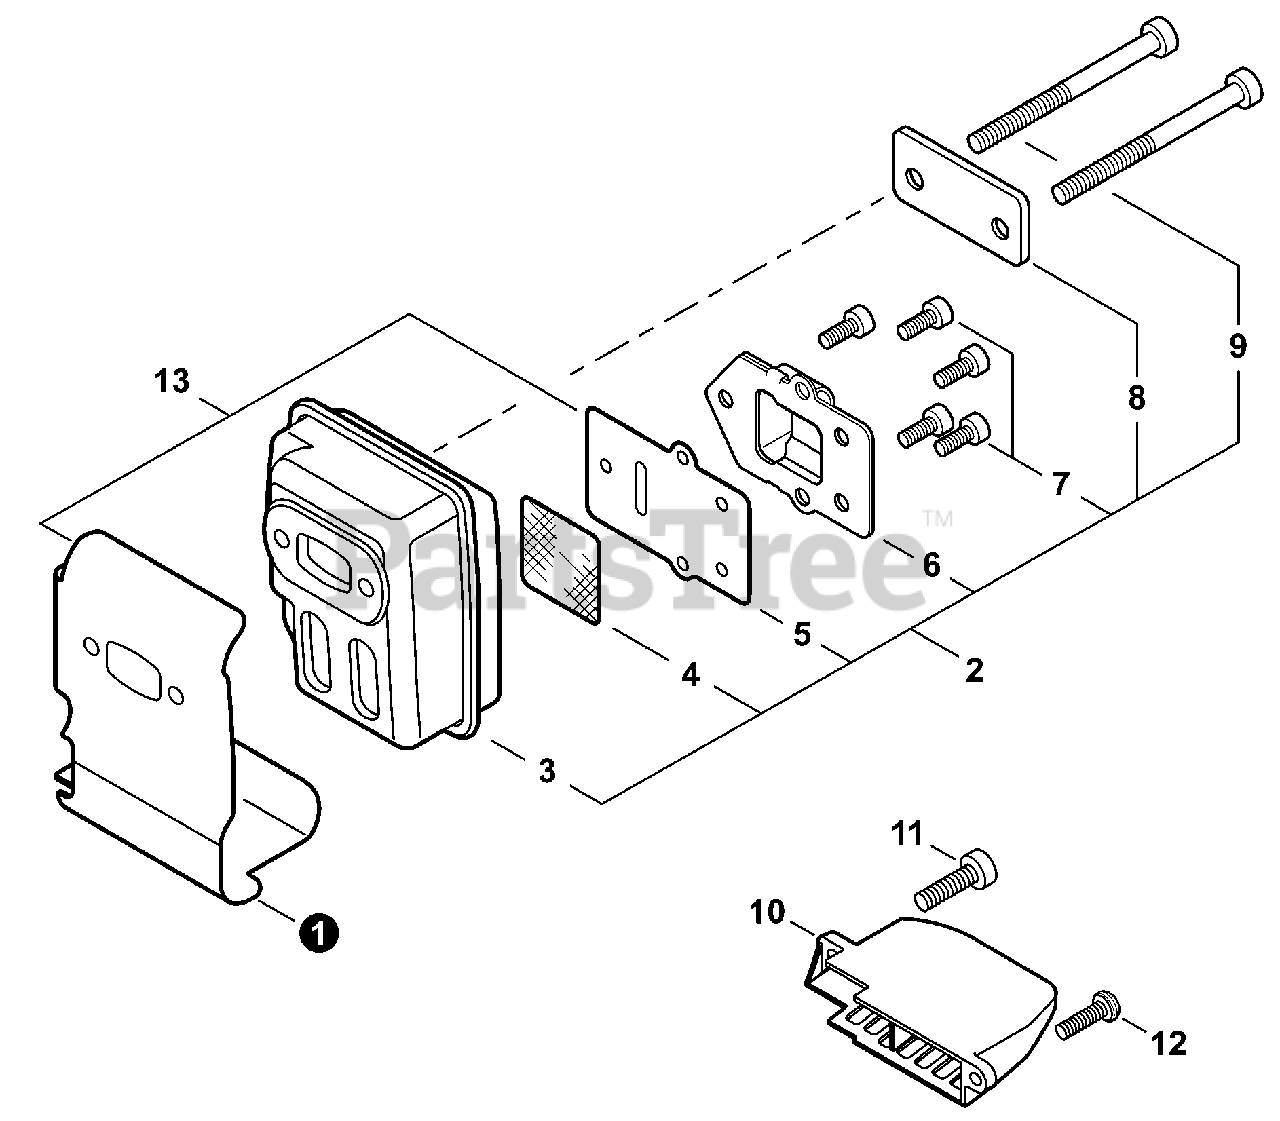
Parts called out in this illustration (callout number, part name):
1	HEAT SHIELD, EXHAUST
2	MUFFLER ASSY
3	MUFFLER
4	SCREEN, SPARK ARRESTER
5	GASKET, EXHAUST
6	GUIDE, EXHAUST
7	BOLT, TORX 4×8
8	PLATE, EYE
9	BOLT, TORX 5×55
10	COVER, MUFFLER
11	BOLT, TORX 5×16
12	BOLT, TORX 5×16
13	GASKET KIT: ENGINE, INTAKE, EXHAUST
